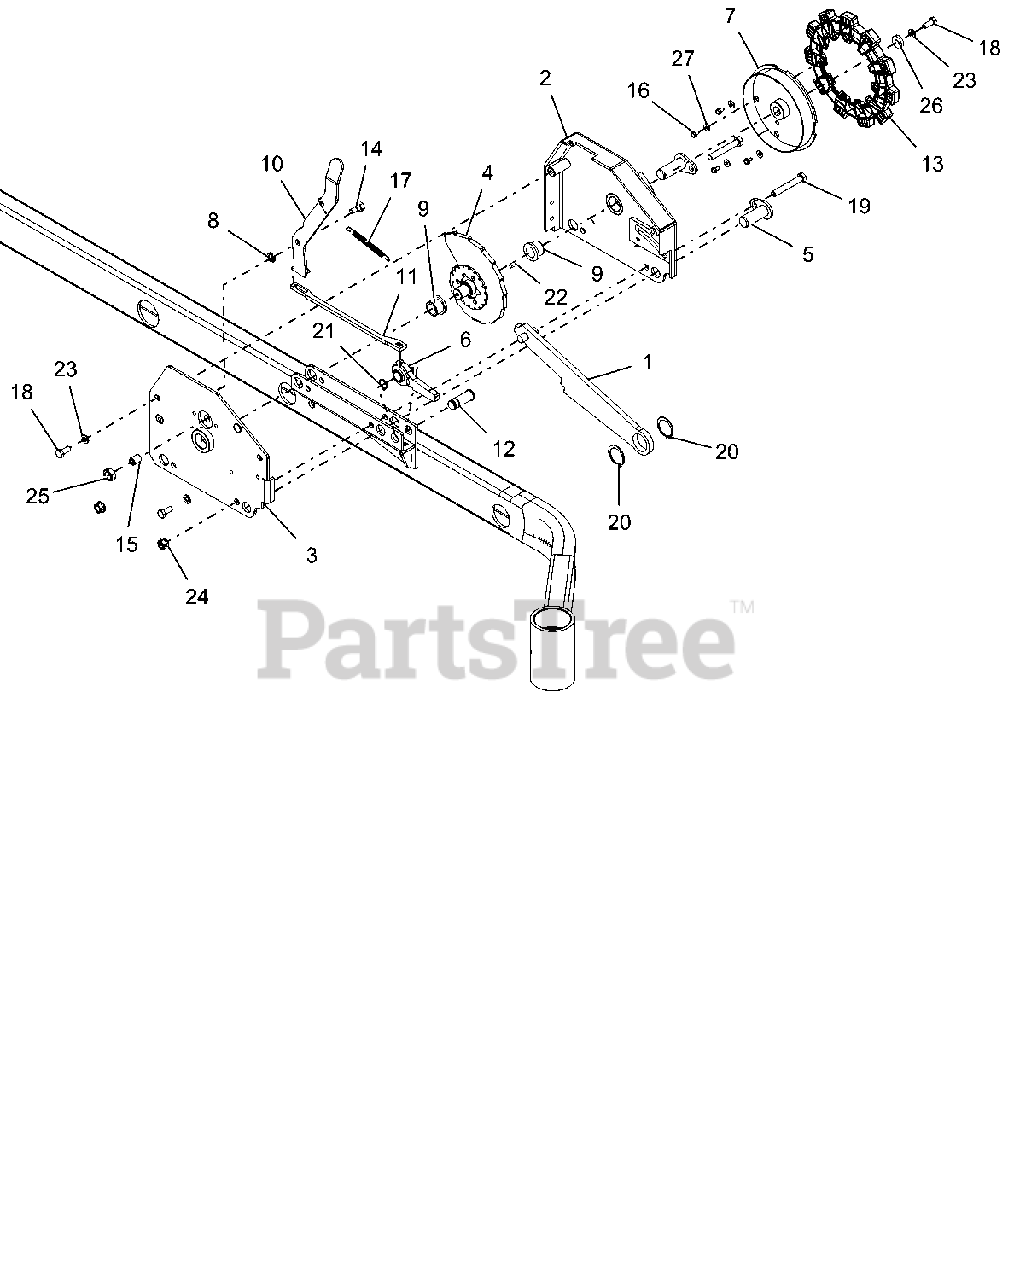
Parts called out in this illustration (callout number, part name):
1	HOC LINK WLDMT - BLK
2	HOC INNER WLDMT - RED
3	WLDMT, HOC OUTER
4	WLDMT, CAM, HOC
5	WLDMT, PIN HOC MOUNTING
6	WLDMT, LOCK PAWL
7	WLDMT, PT400 HOC WHEEL
8	WAVE WASHER .390X.655X.110
9	BUSHING, FLANGE .75X.75X1.0
10	LEVER, TRANSPORT LOCK
11	LINK, TRANSPORT LOCK
12	PIN, CLEVIS .625 SNAP RING
13	WHEEL, HOC
14	BOLT, SHLDR .31-18 X .25
15	BALL SPRING PLUNGER, .500-13
16	SCR-TAP 10-24X.375 PRE-COAT 80
17	SPRING, EXT
18	@BLT-HEX .31-18X.75 GR5 YWZC
19	@BLT-HEX .38-16X2.50 GR5 YWZC
20	RG-RET-EXT 1.25 X .050
21	RG-RTNG-EXT .625X.050
22	KEY-SQ .188X.188X.375
23	@WSHR-LK .31X.078 REG YWZC
24	NUT-LK-CTR-FLG .38-16 YWZC
25	NUT-JAM .50-13 YWZC
26	WSHR-FL-STL .328X.87X.179 YWZC
27	@WSHR-FL-STL.219X.50X.049 YWZC
